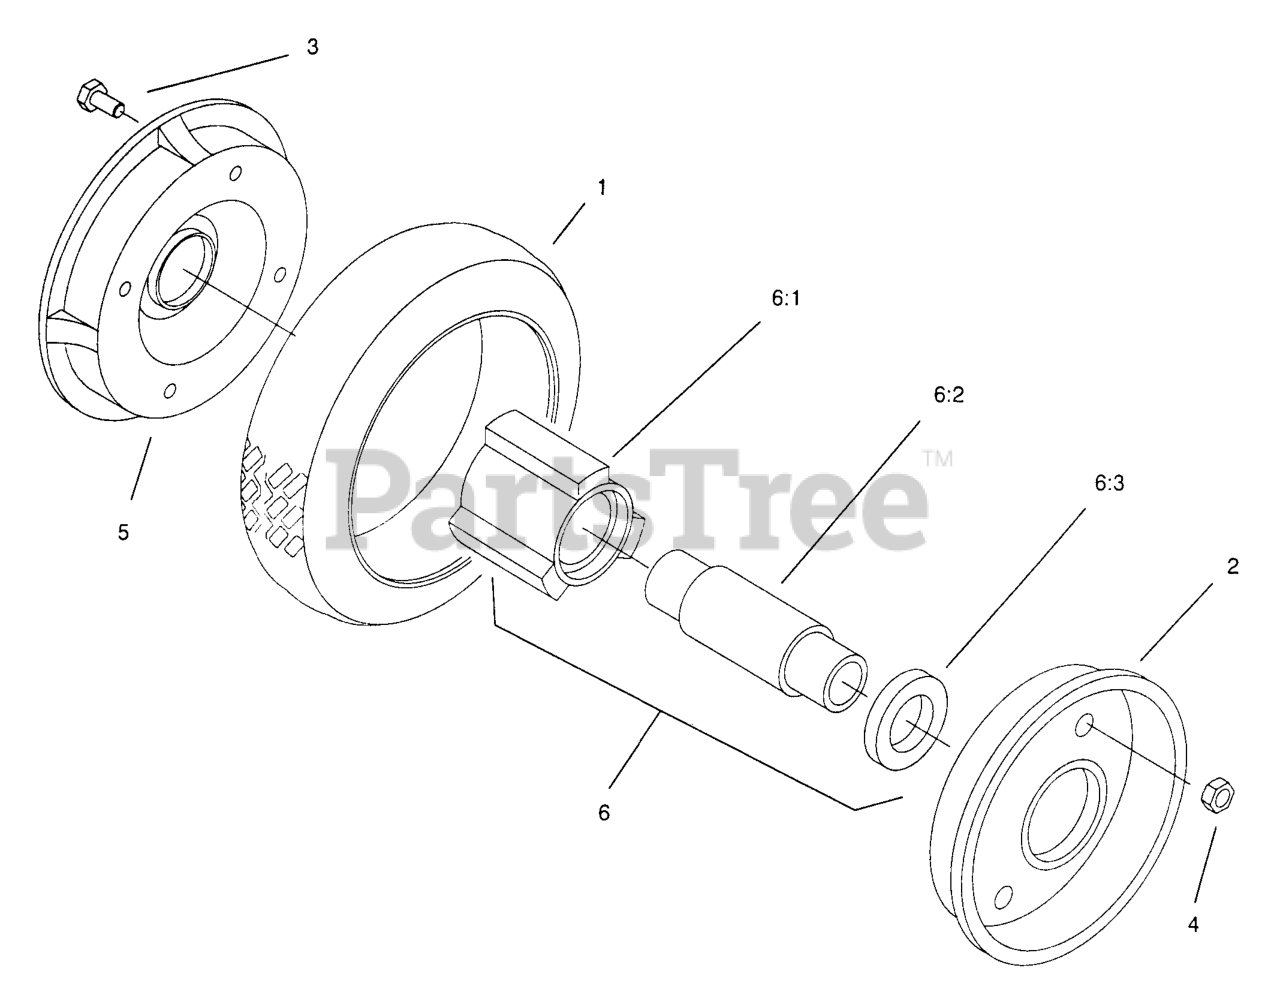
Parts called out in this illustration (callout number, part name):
3	SCREW-HH
4	NUT-LOCK, NI
6	Hub & Bearing Asm
6:1	HUB-BEARING
6:2	SPACER-BEARING
6:3	BEARING-WHEEL
